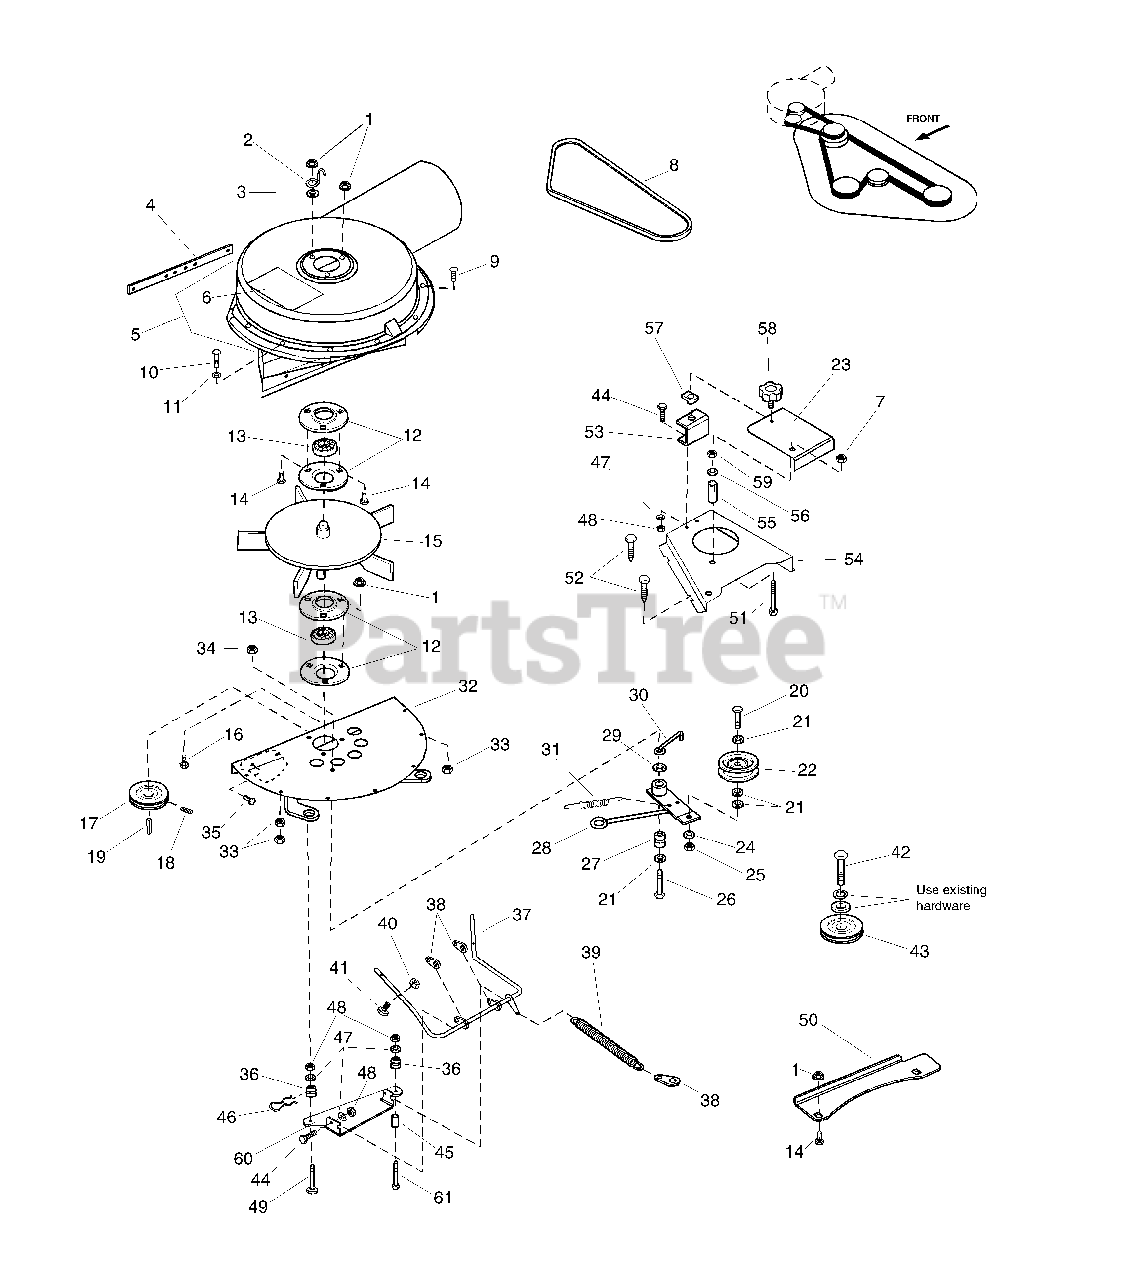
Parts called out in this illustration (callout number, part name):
1	FLANGE LOCKNUT, 5/16-18
3	PUSH NUT, 5/16-18
5	HOUSING, With Decal
6	DECAL,Danger
7	NYLOCK NUT, 5/16-18
8	V-BELT
9	SCREW, Truss Head, 1/4-20
10	CAPSCREW, Hex, 1/4-20 x 1-1/4
11	WASHER, 1/4
12	RETAINER, Bearing
14	CARRIAGE BOLT, 5/16-18 x 3/4
15	FAN ASSEMBLY
16	CAPSCREW, Hex Head, 5/16-18 x 3/4
18	SET SCREW, Torx, 5/16-18 x 5/16
19	KEY, Woodruff
20	CAPSCREW, Hex Head, 3/8-16 x 1-1/2
21	WASHER, 3/8
22	PULLEY, Idler
24	LOCKWASHER, 3/8
25	NUT, 3/8-16
26	CAPSCREW, Hex Head, 3/8-16 x 2
27	BUSHING
28	LEVER ASSEMBLY
29	WASHER, 3/8
31	SPRING, Extension
32	PLATE & BRACKETS ASSEMBLY
33	LOCKNUT, 1/4-20
34	NUT, Hex, 3/8-16
35	SCREW, Taptite, 1/4-20 x 5/8
36	PILOT PIN, Tapered Spacer
37	ROD & ANCHOR ASSEMBLY, Deflector
38	LOCKING TAB
39	SPRING, Extension
40	LOCKNUT, 10-24
41	SCREW, Truss Head, 10-24 x 3/4
42	CAPSCREW, Hex Head, 7/16-14 x 2-1/4
43	PULLEY & HUB ASSEMBLY
44	CAPSCREW, Hex Head, 1/4-20 x 5/8
45	SPACER, 5/8 x 1
46	PIN, Spring
47	LOCKWASHER, 1/4
48	NUT, Hex, 1/4-20
49	CARRIAGE BOLT, 1/4-20 x 1-1/4
50	SUPPORT PLATE
51	CAPSCREW, Hex Head, 5/16-18 x 2-1/2
52	CAPSCREW, Hex Head, Taptite,1/4-20 X 5/8
53	BRACKET, Belt Cover
54	COVER, Arbor
56	LOCKWASHER, 5/16
57	PAL NUT, 5/16-18
59	NUT, Hex, 5/16-18
60	PLATE, Deflector Mounting
61	CAPSCREW, Hex Head, 1/4-20 x 2-1/4
